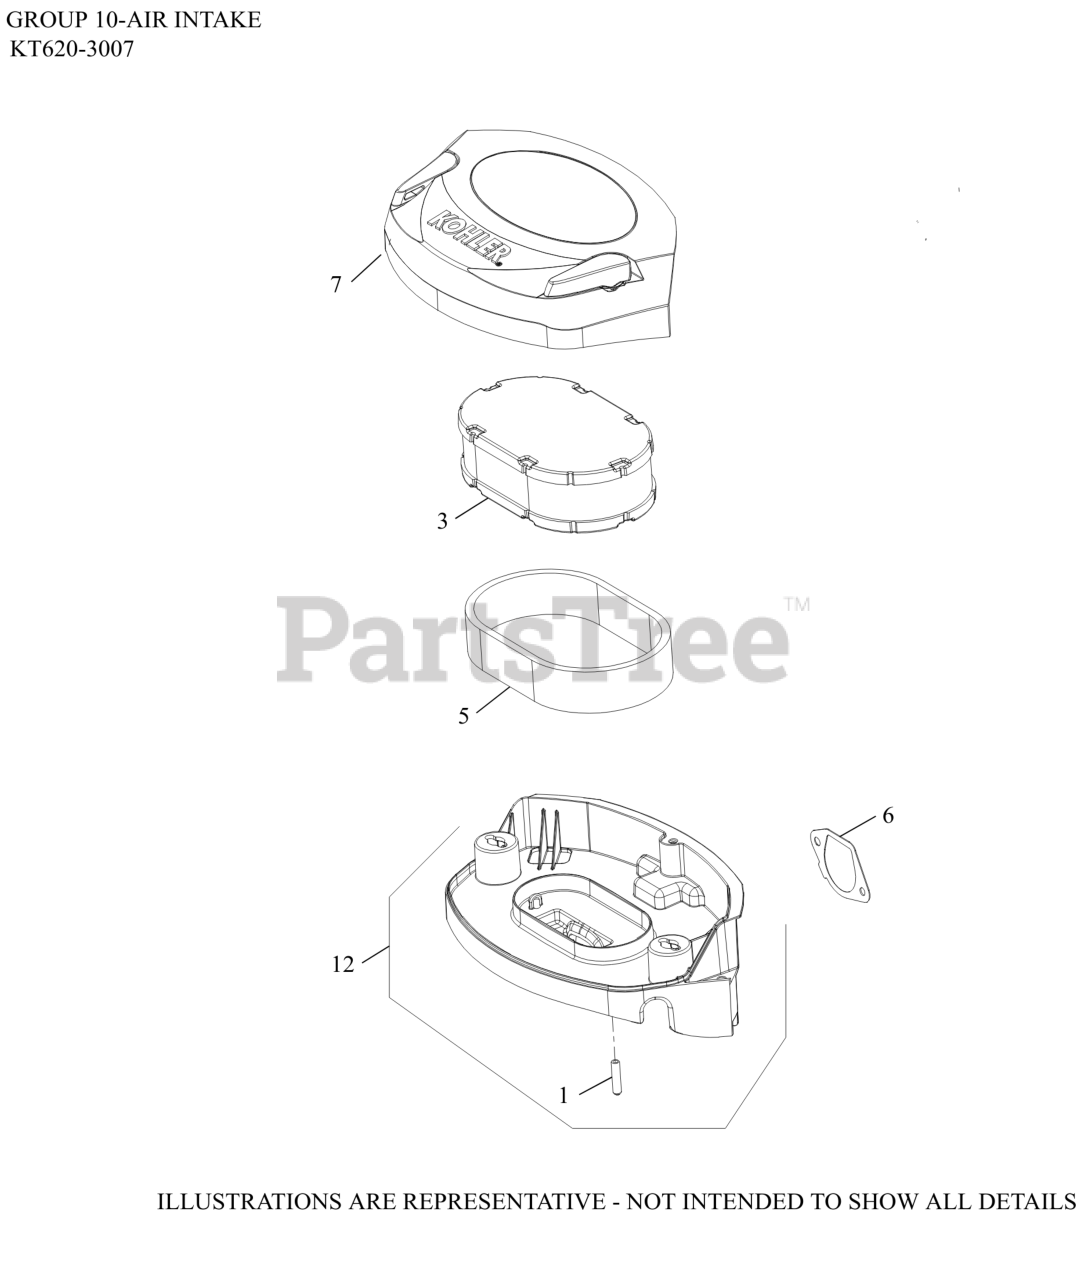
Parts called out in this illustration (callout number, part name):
1	CAP, MASKING
3	ELEMENT, AIR FILTER
5	ELEMENT, PRE-CLEANER
6	GASKET, AIR CLEANER BASE
7	COVER ASSEMBLY, AIR CLEANER
12	BASE ASSY, AIR CLEANER
